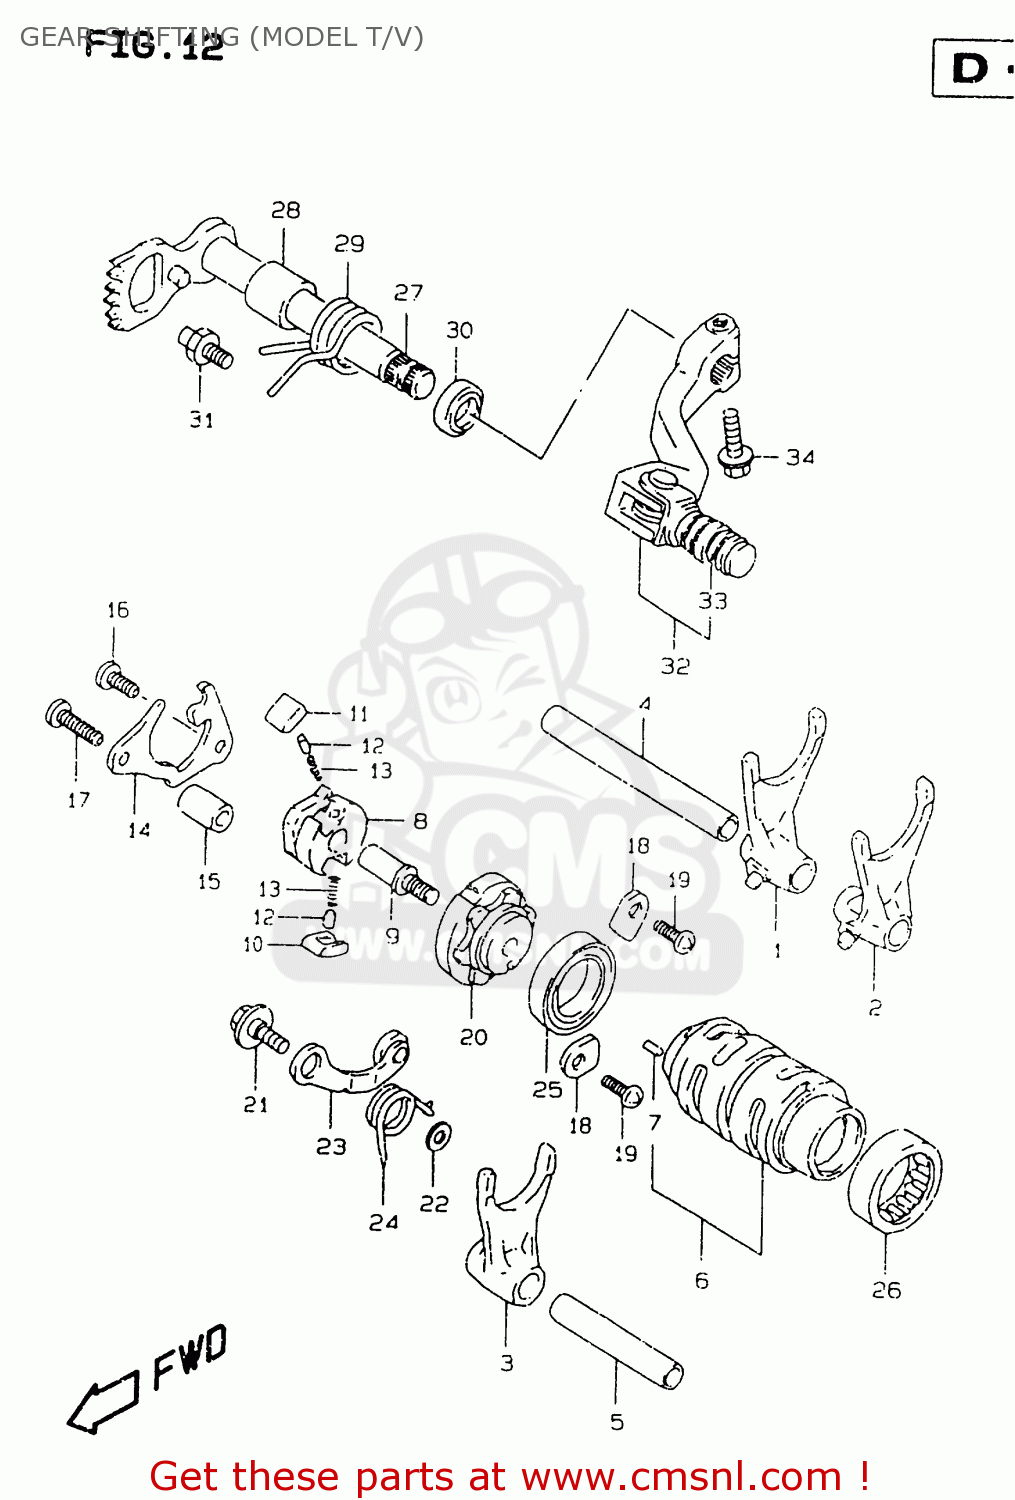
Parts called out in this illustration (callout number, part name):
1	FORK,GEAR SHIFT NO.1
2	FORK,GEAR SHIFT NO.2
3	FORK,GEAR SHIFT NO.3
4	SHAFT,GEAR SHIFT FORK
5	SHAFT,GEAR SHIFT FORK
6	CAM,GEAR SHIFT
7	PIN
8	GEAR,GEAR SHIFT CAM DRIVEN
9	PIN,SHIFT CAM DRIVEN GEAR
10	PAWL,GEAR SHIFT NO.1
11	PAWL,GEAR SHIFT NO.2
12	PIN(5X8)
13	SPRING
14	LIFTER,GEAR SHIFT POLE
15	SPACER(6.2X12X18)
16	SCREW
17	SCREW
18	RETAINER
19	SCREW
20	PLATE,SHIFT CAM STOPPER
21	BOLT(6X14.3)
22	WASHER
23	STOPPER,SHIFT CAM
24	SPRING
25	BEARING
26	BEARING(30X37X12)
27	SHAFT,GEAR SHIFT
28	SPACER(14X20X17.5)
29	SPRING
30	SEAL,OIL(14X22X6)
31	STOPPER,GEAR SHIFT CAM
32	LEVER ASSEMBLY,GEAR SHIFTING
33	RUBBER,GEAR SHIFT PEDAL
34	SCREW
